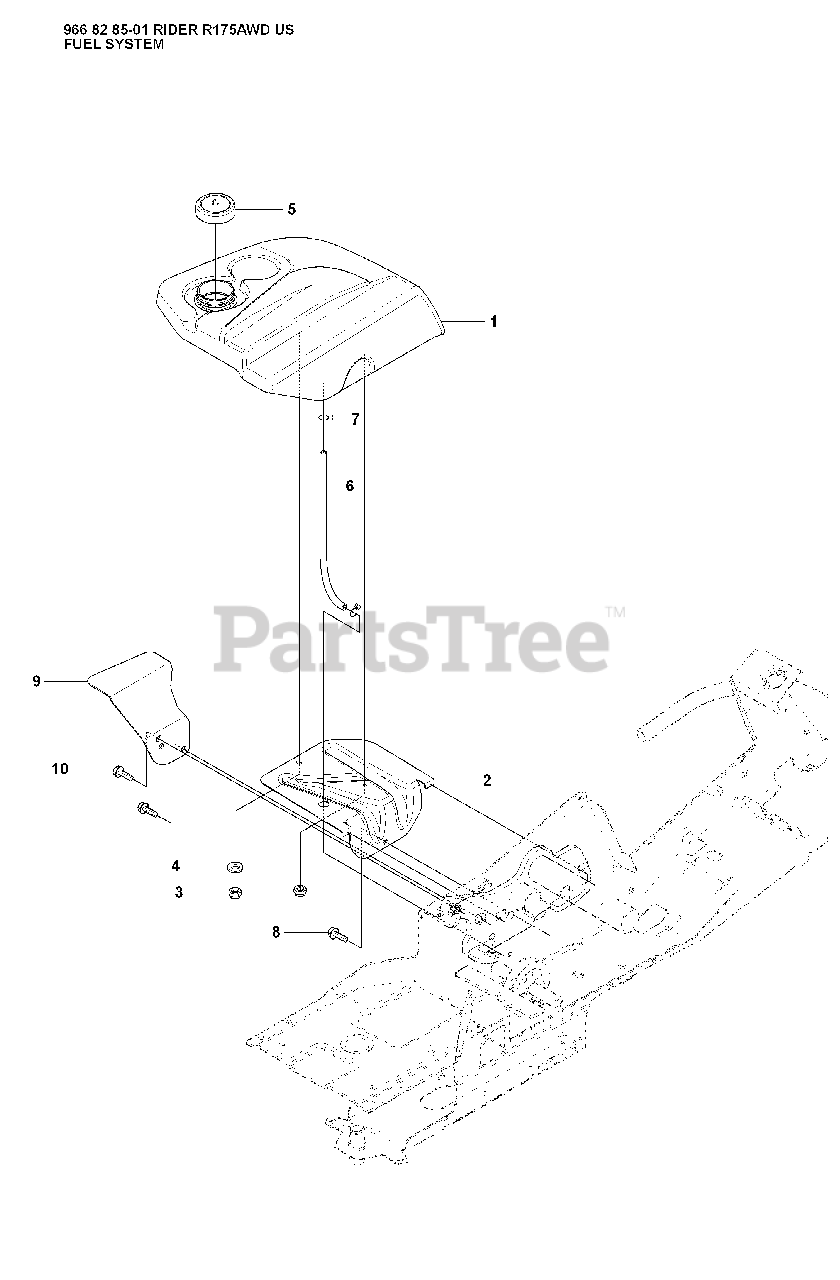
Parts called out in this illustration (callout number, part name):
3	LOCKNUT M6
4	WASHER
10	Screw, M10 X 25
